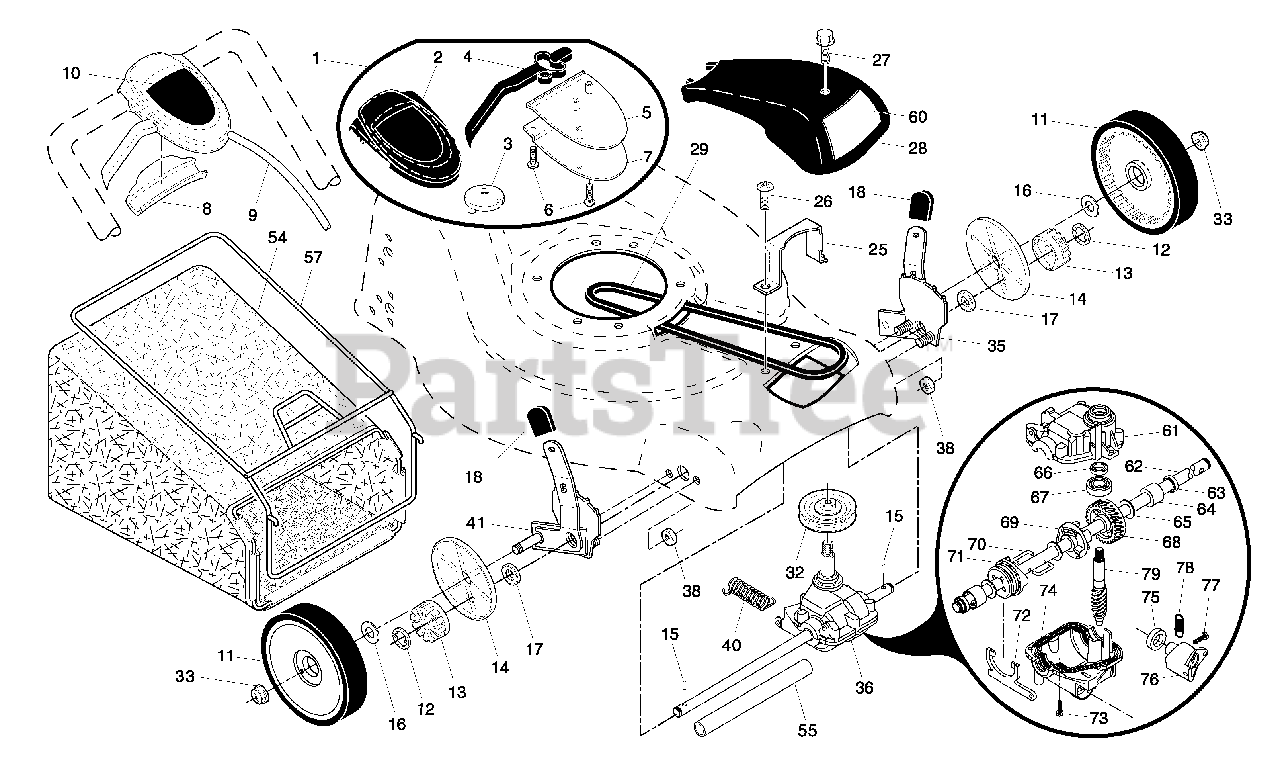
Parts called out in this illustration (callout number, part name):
1	Drive Control Assembly
2	Cover, Drive Control, Upper
4	Lever, Drive Control
5	Cover, Drive Control, Lower
7	Mounting Bracket, Drive Control
8	Cap, Drive Control
9	Cable, Drive
10	Decal, Drive Cover
11	Wheel & Tire Assembly
13	Pinion
14	Dust Cover
15	Pawl, Drive
16	Washer 1/2 x 1-1/2 x .134
17	Bearing, Wheel Adjuster
18	Selector Knob
25	Belt Keeper
26	Screw
27	Pan Head Tapping Screw #10-24 x 2-3/4
28	Drive Cover
32	Drive Pulley
33	Locknut, Hex
35	Kit, Wheel Adjuster, LH
36	Gearcase Assembly, Complete
38	Locknut, Hex 1/4-20
41	Kit, Wheel Adjuster, RH
54	Grassbag Assembly
55	Driveshaft Cover
57	Frame, Grassbag
61	Case, Upper
62	Shaft, Output
63	Seal, Output Shaft
66	Seal, Worm Shaft
67	Bearing, Ball
68	Gear, 27 Teeth
69	Fixed Dog Clutch
71	Movable Dog Clutch
73	Screw, Case
74	Case, Lower
75	Seal, Lever
77	Screw, Lever
79	Shaft, Worm
